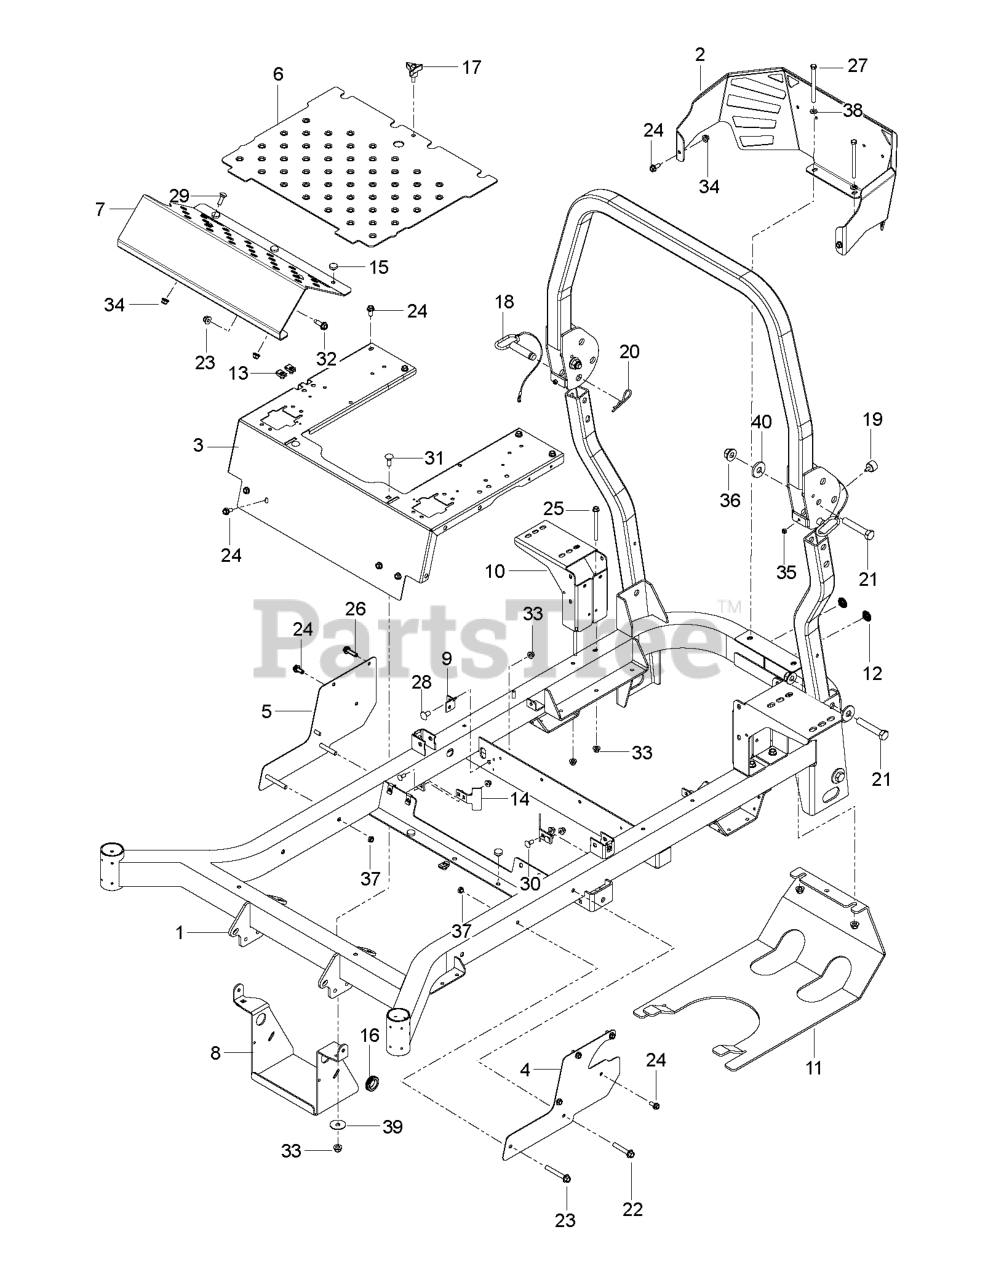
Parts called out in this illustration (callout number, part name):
1	FRAME.KIT.W/DECALS.REDMAX.672
3	SUPPORT SEAT CONTROL SNAPPER R
4	BRACKET SIDE LH SNAPPER RED X6
5	BRACKET SIDE RH SNAPPER RED X6
6	KIT.PLATE.FLOOR.W/DCL.REDM.672
7	PLATE.FOOTREST.PNT.G-BLACK
8	BRACKET.PNT.BATTERY.BLK
9	BRACKET.DAMPENER.BLACK
10	MOUNT, TANK, ZT BLK
11	GUARD SKID PNT 498
12	CAP.PLUG.BP-1.BLACK
13	U-CLIP 5/16-18 NUT RETAINER
14	STOP, DECK, EZ+
15	GROMMET, BUMPER
16	RUBBER GROMMET
17	KNOB W/STUD
18	PIN, ROPS
19	BUMPER, MALE STUD, 1/4-20
20	PIN HAIR .148 X 2-15/16 #210
21	5/8-11 X 3-1/2 HHB GRADE 5
22	HHFS 3/8-16 X 2.5 GR 5 ZD
23	HHFS 3/8-16 X 2-3/4 GR5 ZD
24	HHFS 5/16-18 X 3/4
25	BOLT.HEX.FLNG.5/16-18X3.75
26	HHFS 5/16-18 X 1.25 TPBLT GD 5
27	HCS 5/16C X 4
28	RHSNB 3/8-16 X 3/4 GR 5 BLK ZN
29	RHSNB 5/16C X 1
30	BOLT 5/16C X 3/4" CARRIAGE
31	RHSNB 3/8C X 1
32	RP BLT 5/16-18 X 1 THRD FORM D
33	NUT 3/8-16 HEX FLG NYLOC ZD
34	5/16-18 NYLOC FLANGE NUT
35	RP_NUT 1/4-20 NYLOC
36	NUT 5/8-11 FLG NYLOC ZD
37	NUT HEX 3/8-16 NYLON, THIN
38	WASHER
39	WASHER.13/32X1-1/2X16GA
40	WASHER, 5/8 FLAT
